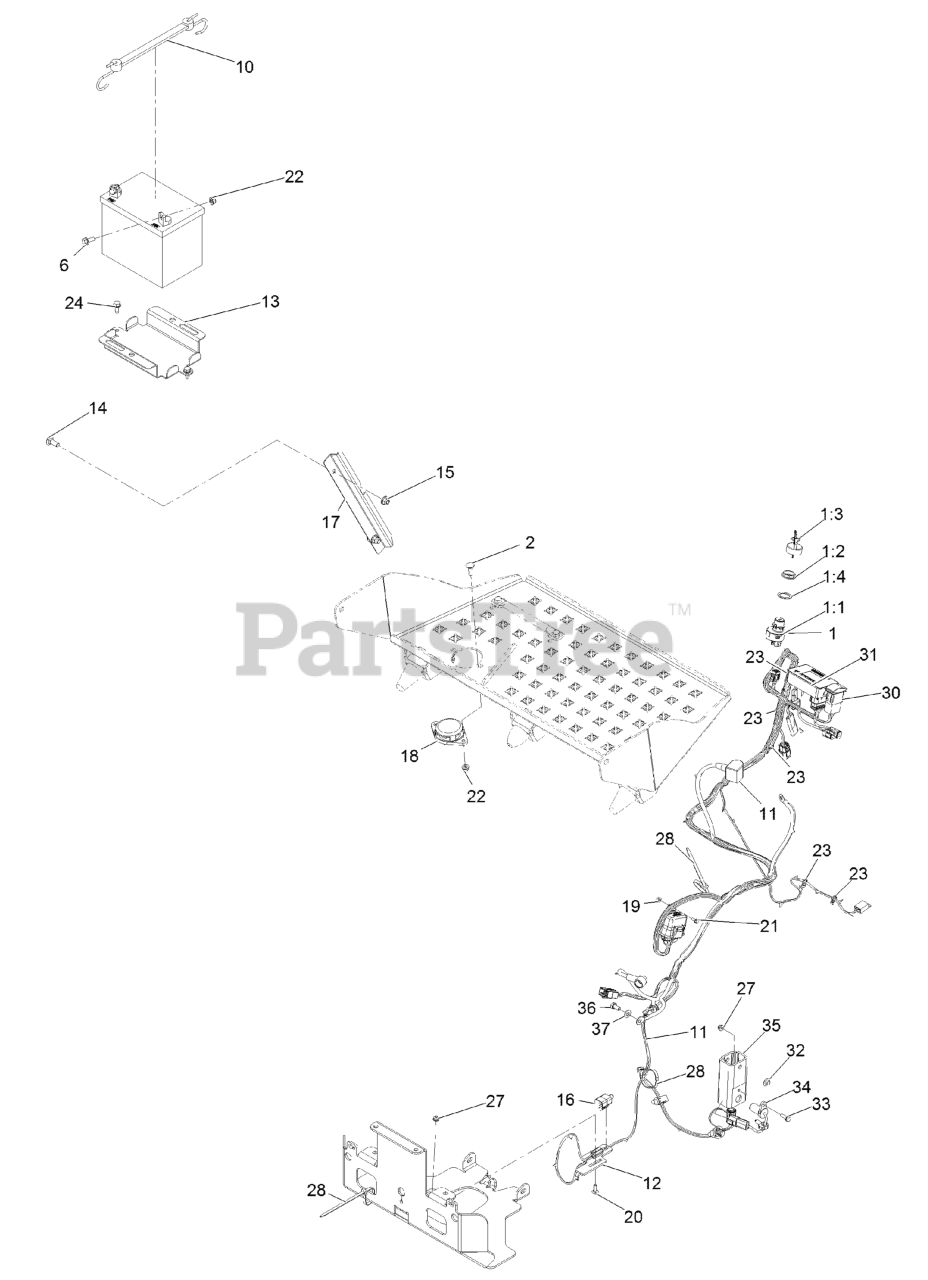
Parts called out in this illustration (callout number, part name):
1	KEYS-IGNITION (SPARE PAIR
1	KEY-IGNITION
2	BOLT-CARR
5	METER-HOUR
6	SCREW-HHF
8	CABLE-BATTERY, BLACK
9	POSITIVE BATTERY CABLE AS
9:1	INSULATOR-BATTERY
9:2	INSULATOR-SOLENOID
10	HOLDDOWN-BATTERY
11	HARNESS-WIRE
11:1	CAP-PLUG
11:2	FUSE-BLADE TYPE, 20 AMP
12	MOUNT-SWITCH
13	BRACKET-BATTERY
14	BOLT-CARR
15	NUT-HF, NI
17	GUARD-HARNESS
18	SWITCH-SEAT
19	NUT-LOCK, NI
20	BOLT-CARR
21	SCREW-HWH
22	NUT-HF, NI
23	TIE-CABLE
24	Screw-HWH 5/16-18 X 3/4 Tf
25	SCREW-HH
26	WASHER-PLAIN
28	TIE-PLASTIC
